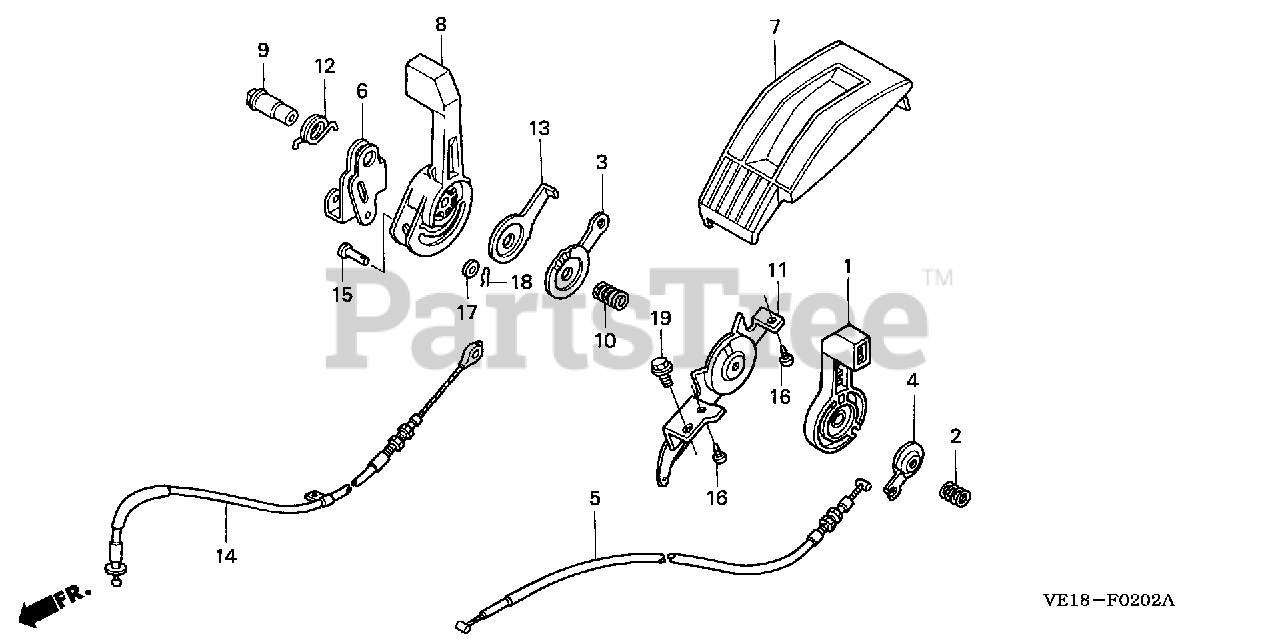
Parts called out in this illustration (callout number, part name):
1	LEVER, THROTTLE
2	SPRING, THROTTLE LEVER
3	SEAT, SPRING
4	SEAT, SPRING
5	CABLE, THROTTLE
6	ARM, CHANGE LEVER
7	COVER, CONTROL
8	LEVER, CHANGE
9	NUT, CHANGE LEVER
10	SPRING, CHANGE LEVER
11	PLATE, STOPPER
12	SPRING, ARM RETURN
13	PLATE, THRUST
14	CABLE, CHANGE
15	PIN (6X22)
16	SCREW, TAPPING (5X12)
17	WASHER, PLAIN (6MM)
18	PIN, LOCK (6MM)
19	BOLT, FLANGE (6X10)
